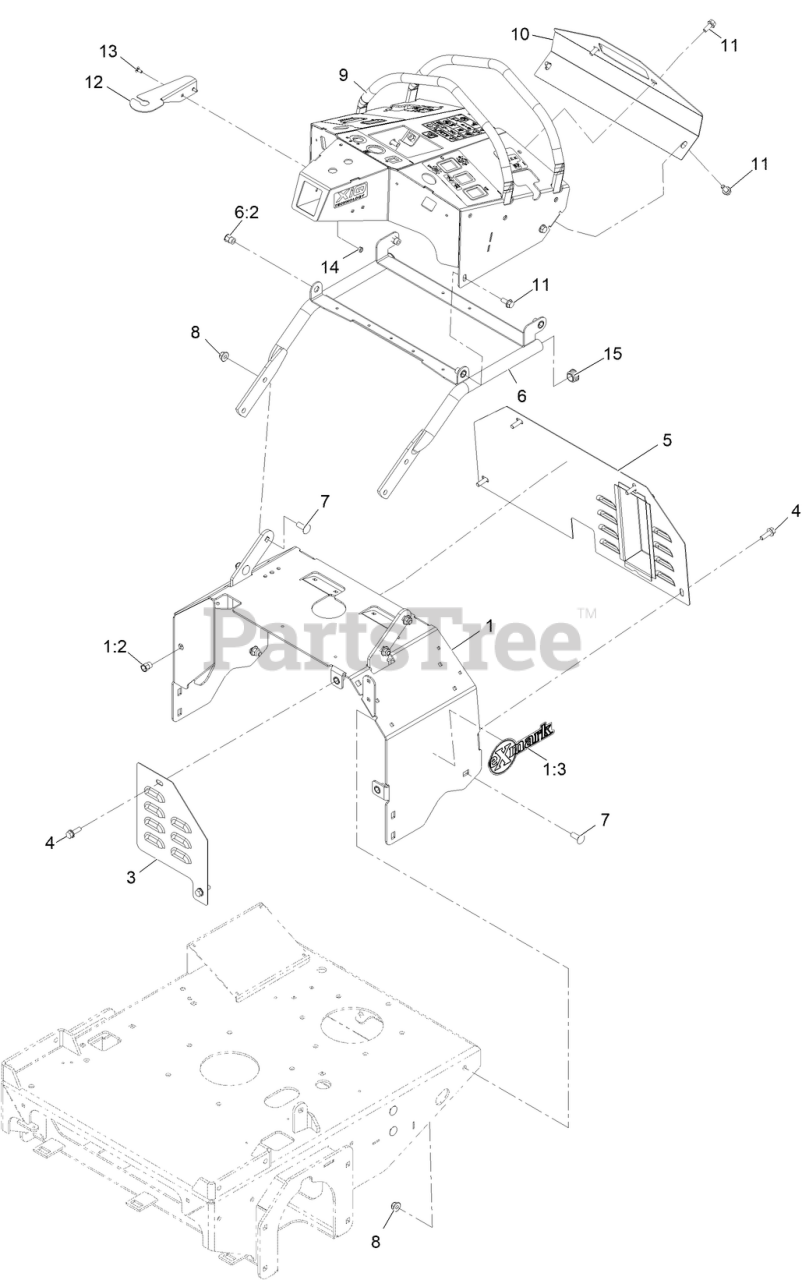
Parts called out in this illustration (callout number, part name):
1	ASM FUEL TANK SUPPORT
1:2	Nut-Clinch
1:3	DECAL-EXMARK LOGO
3	PANEL-FRONT, LH
4	SCREW-HHF
5	REAR ACCESS PANEL
6	ASM CONTROL PANEL SUPPORT
6:2	Nut-Clinch
7	SCREW-CARR
8	NUT-HF, NI
9	ASM CONTROL PANEL
10	PLATE-CONTROL PANEL ACCESS
11	SCREW-HHF
12	BRACKET-ANTENNA, CELL
13	BOLT-CARR
14	NUT-LOCK, NI
